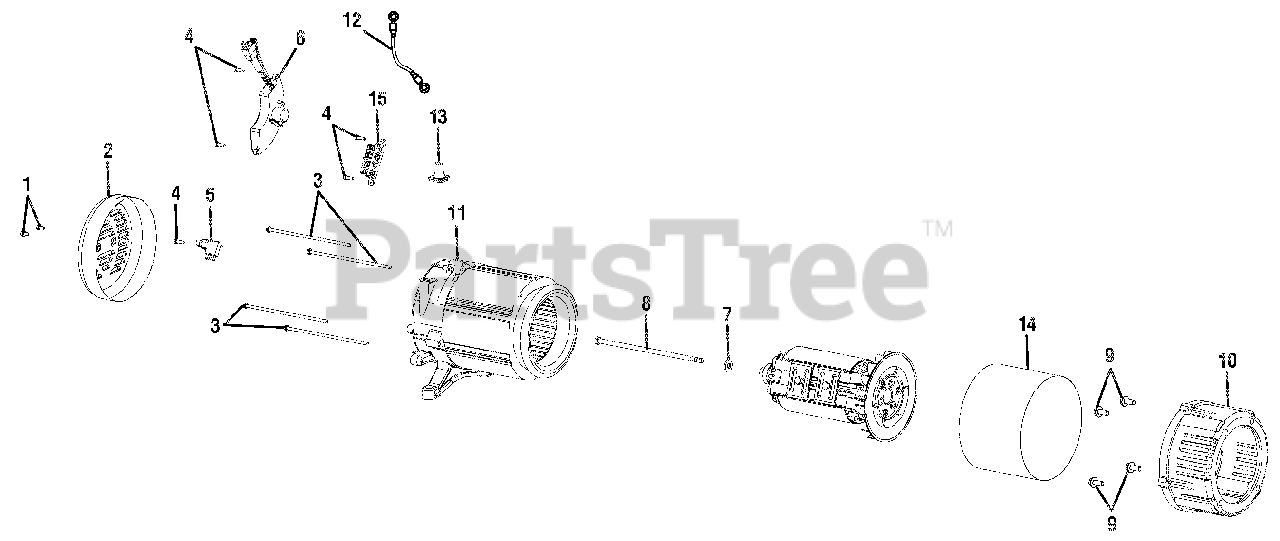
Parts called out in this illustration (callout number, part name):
1	Bolt (M5 x 10 mm, FlangeHex Hd.)
2	Brush Cover
3	Bolt (1/4-20 x 6 in., Hex Hd.)
4	Bolt (M5 x 16 mm, Flange Hex Hd.)
5	Brush Assembly
6	Automatic Voltage Regulator
7	Washer (5/16 in.)
8	Bolt (5/16-24 x 230 mm, Hex. Hd.)
9	Bolt (3/8-16 x 1-1/4 in.)
10	Engine Adapter
11	Bearing Housing
12	Bonding Wire
13	Rubber Boot
15	Terminal Block
